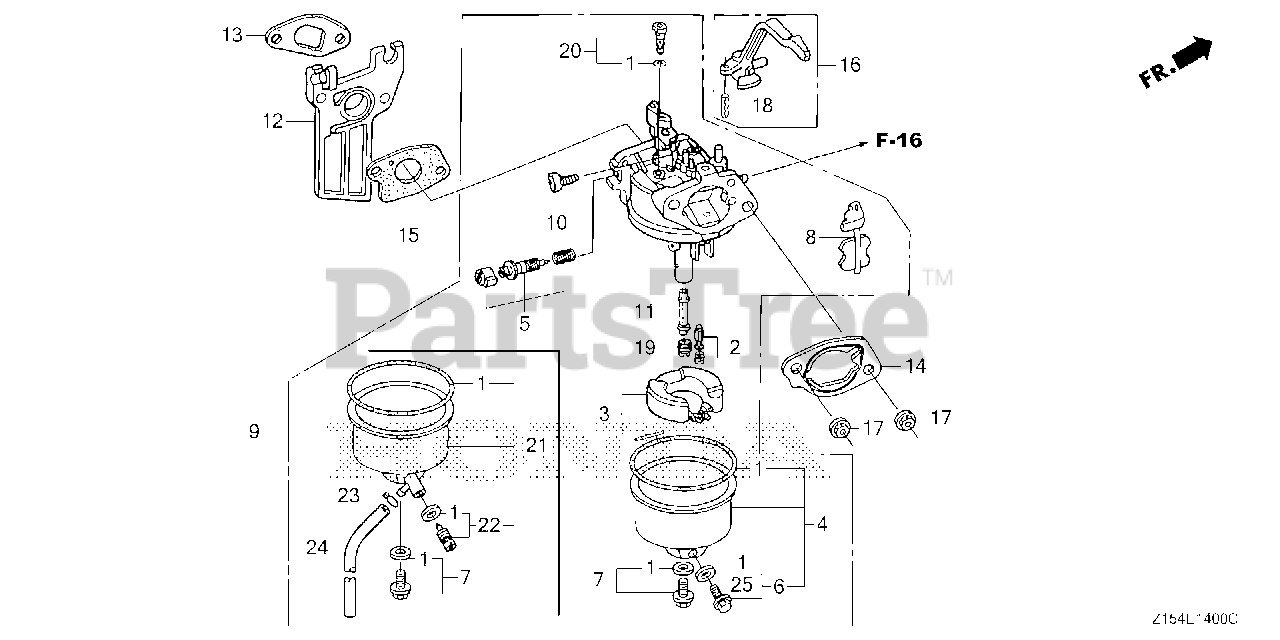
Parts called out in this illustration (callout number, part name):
1	GASKET SET
2	VALVE SET, FLOAT (SEAT NOT INCLUDED)
4	CHAMBER SET, FLOAT
5	SCREW SET, PILOT
6	SCREW SET, DRAIN
7	SCREW SET
9	CARBURETOR ASSY. (BE67N A)
10	SCREW, THROTTLE STOP
11	NOZZLE, MAIN
12	INSULATOR, CARBURETOR (JLH)
13	GASKET, INSULATOR
13	GASKET, INSULATOR (NINGBO SIL GASKET)
14	SPACER, CARBURETOR
15	GASKET, CARBURETOR
15	GASKET, CARBURETOR (NINGBO SIL GASKET)
16	LEVER, CHOKE
17	NUT, FLANGE (6MM)
18	PIN, SPRING (2X12)
19	JET, MAIN (#72)
19	JET, MAIN (#68)
19	JET, MAIN (#70)
20	JET SET, PILOT (#35)
